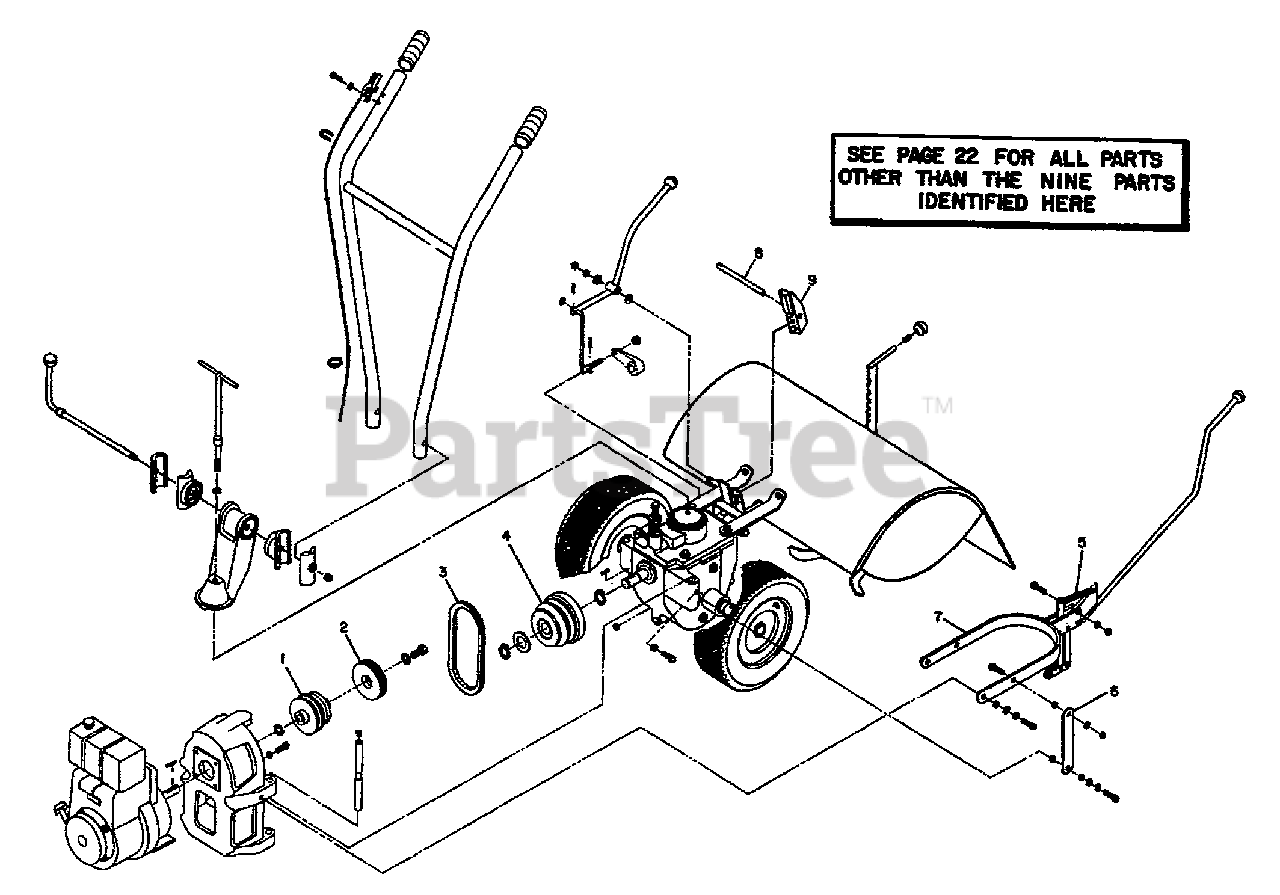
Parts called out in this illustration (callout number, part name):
1	PULLEY-ENG MACH
2	KIT-ADJ BLOCK/REV DISC
3	BELT-V
4	PULLEY-TRANS-MACH
5	SPRING-.436 X 3.25
6	BAR-CLUTCH YOKE
7	KIT-LEVER FWD/REV-HORSE 2
8	BAR-ADJUST
9	KIT-ADJ BLOCK 4 SP
